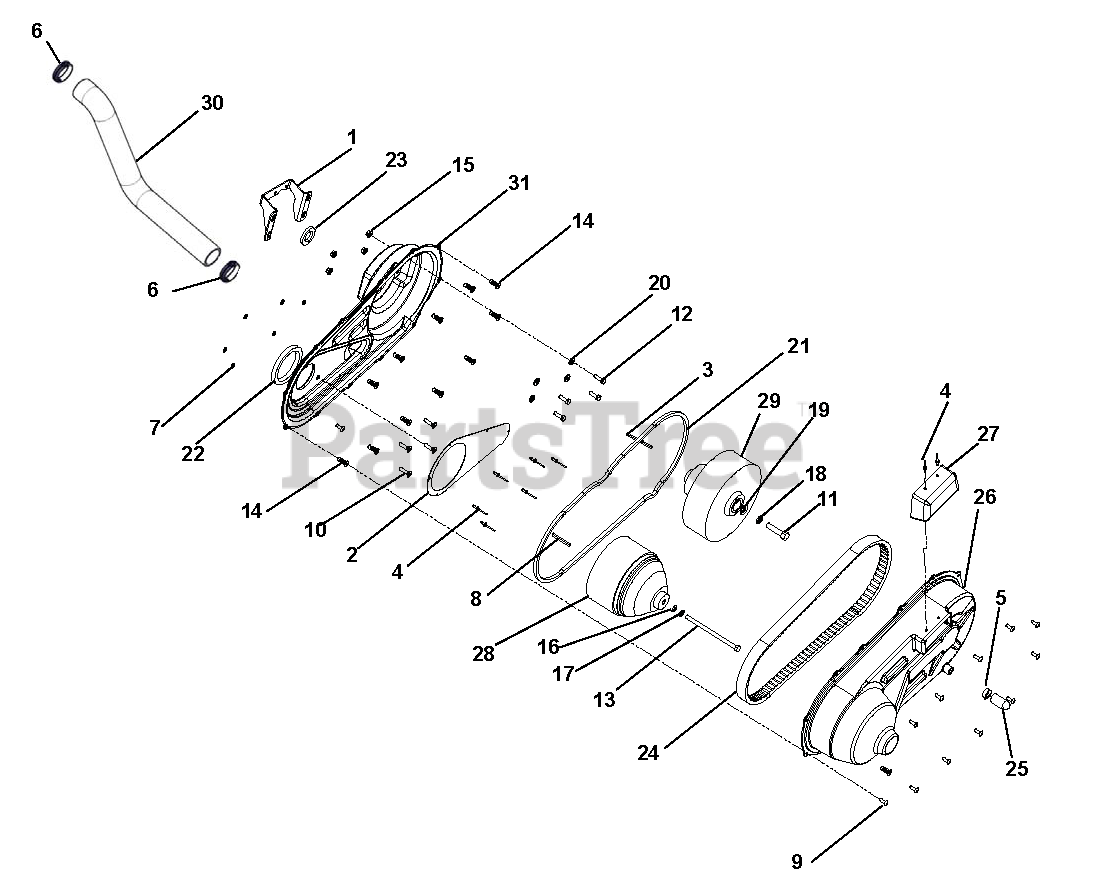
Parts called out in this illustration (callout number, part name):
1	BRACKET, CVT COVER TO TRANS.
2	INLET DUCT, CVT
3	KEY 3/16 X 3
4	RIVET POP 3/16 .126-.250
5	SPRING CLAMP 1" OD HOSE
6	CLAMP,HOSE,WRM DRV,1.81X2.75
7	RIVET POP WASHER 3/16
8	KEY .187 X .247 X 2.25 LG
9	SCR-MCH .25-20X.75 TXTR YWZC
10	BOLT, 5/16-24 X .75 HSFHCS
11	BLT-HEX .50-20X2.0 GR5 YWZC
12	@BLT-HEX .31-18X1.00 GR5 YWZC
13	HHCS 3/8-24X6 1/2 GR5 PLT
14	INSERT, 1/4-20 ARS4-420-280
15	@NUT-LK-TOP-FLG .31-18 YWZC
16	@WSHR-FL-STL.406X.812X.065 YWZ
17	@WSHR-LK .38X.094 REG YWZC
18	@WSHR-LK .50X.125 REG YWZC
19	@WSHR-FL-STL.531X1.06X.095YWZC
20	WASHER FLAT 5/16 NEOPRENE PLT
21	SEAL, MAIN TRUCK CVT HOUSING
22	GASKET, CVT, FOAM
23	SEAL, CVT TO TRANSAXLE
24	BELT, CVT -LP3
25	CAP, DRAIN 7/8 OD PORT
26	ENCLOSURE, CVT OUTER
27	OUTLET DIVERTER, CVT
28	CLUTCH,DRIVER,25MPH
29	DRIVEN, CVTECH POWERBLOC-LP3
30	INTAKE TUBE, CVT ENCLOSURE
31	ENCLOSURE, CVT INNER
